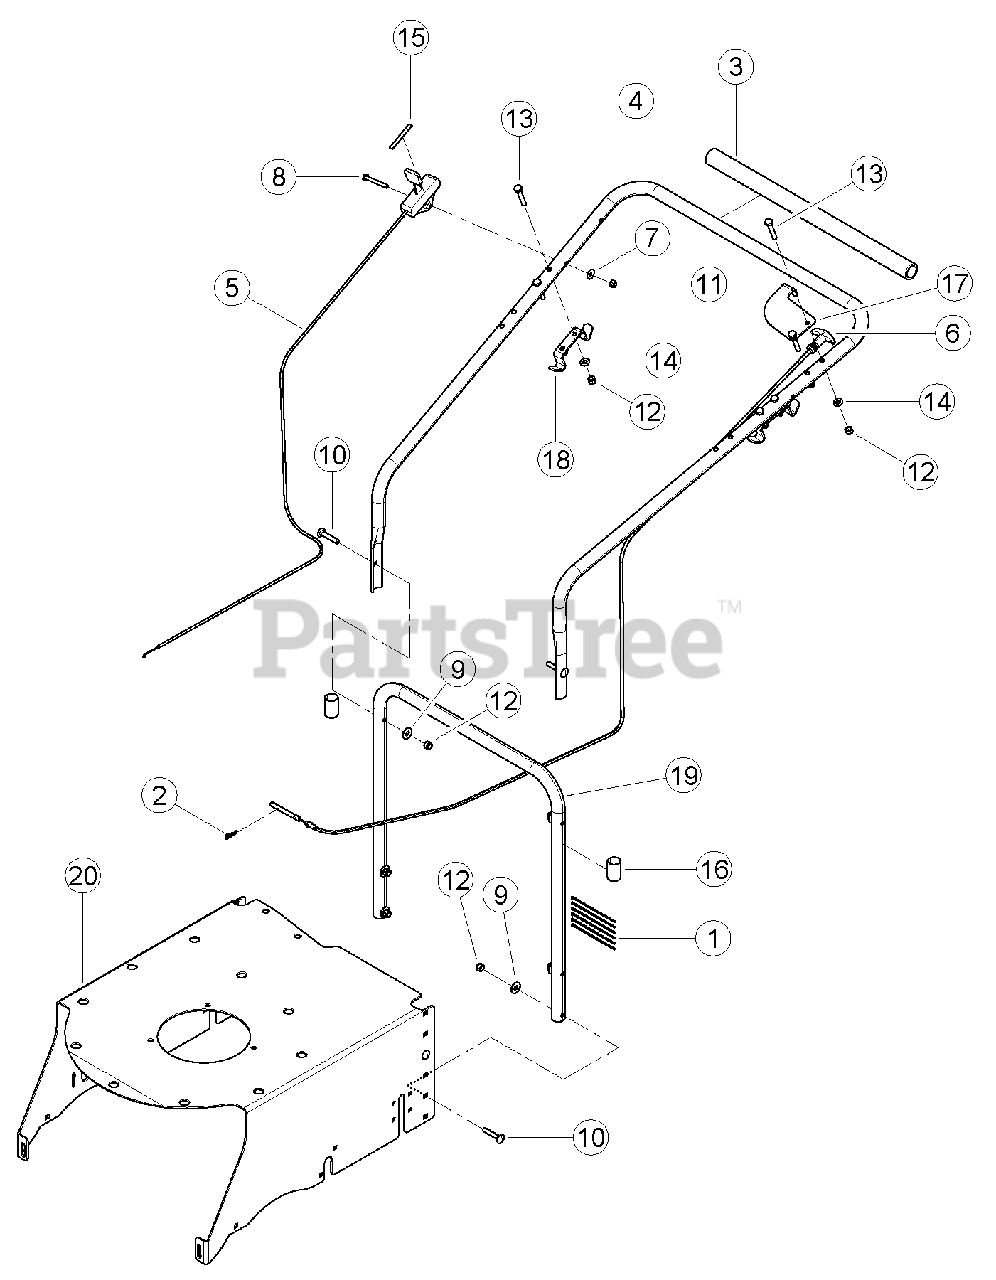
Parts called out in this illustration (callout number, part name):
1	STRAP, 4-1/2 BLACK TIE
2	CLIP, HAIRPIN ZP
3	PAD, FOAM HANDLEBAR
4	HANDLEBAR, BEARVAC UPPER
5	CONTROL, THROTTLE
6	CONTROL, HEIGHT ADJUSTMENT
7	WASHER, 1/4 FLAT ZP
8	BOLT, 1/4 X 2 HEX HD GR5 ZP
9	WASHER, 5/16 FLAT ZP
10	BOLT, 5/16 X 1-3/4 CRG GR5 ZP
11	NUT, 1/4 NE NYLOCK ZP
12	NUT, 5/16 NE NYLOCK ZP
13	BOLT, 5/16-18 X 1-3/4 HCS GR5 ZP
14	WASHER, 5/16 SAE FLAT ZP
15	DECAL, THROTTLE
16	PLASTIC CAP 7/8
17	BRACKET, BEARVAC CABLE MOUNT
18	BRACKET, BAG HANGER
19	HANDLEBAR, LOWER BEARVAC
20	SUPPORT, BEARVAC FRAME
